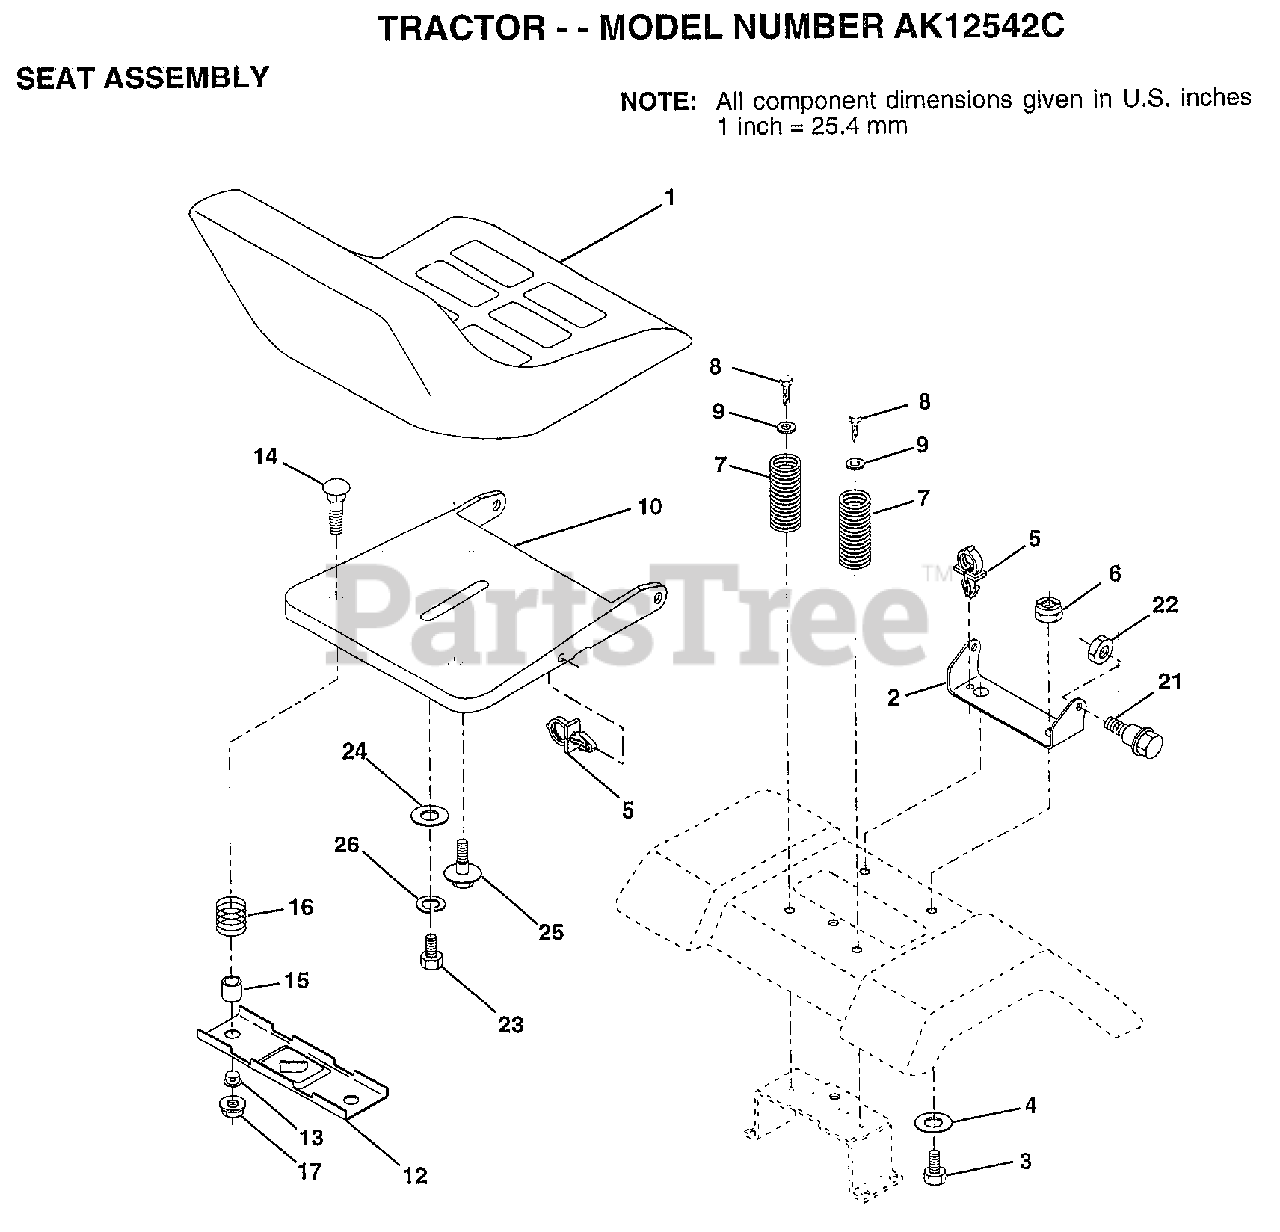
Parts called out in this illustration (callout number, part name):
2	BRACKET PVT SEAT
3	BOLT
4	WASHER PM
5	CLIP.PUSH-IN.HING
6	NUT
7	SPRING COMPRESSIO
8	SCREW GTV
9	WASHER
10	PAN-SEAT
12	BRKT SWITCH
13	BUSHING
14	BOLT-RD HD SQ NK
15	SPLIT SPACER
16	SPRING
21	"BOLT,SHOULDER"
23	BOLT
24	WASHER
25	"BOLT,SHOULDER"
26	LOCKWASHER
